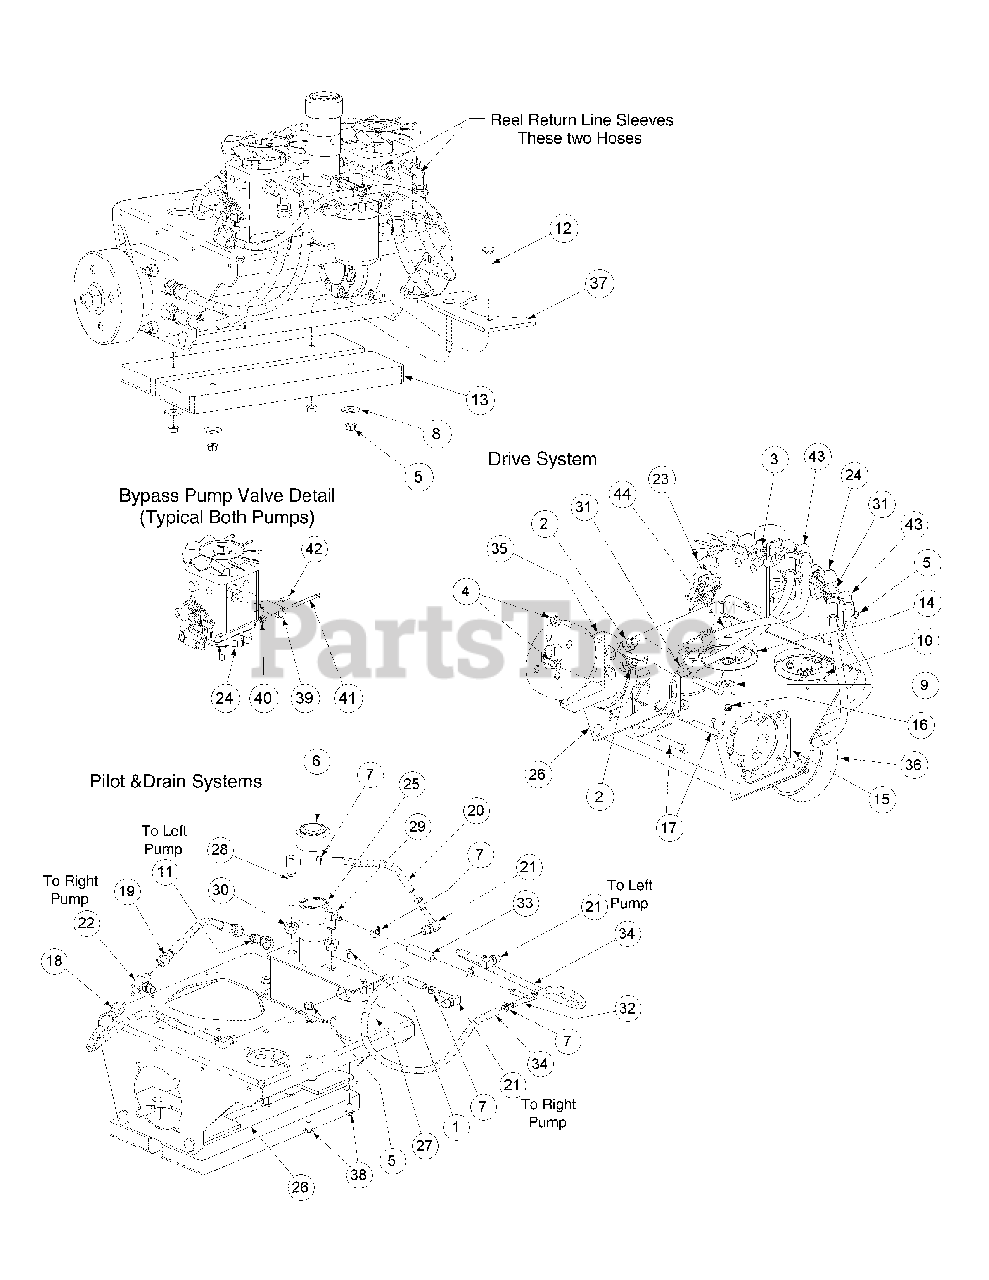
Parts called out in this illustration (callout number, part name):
1	Hex Cap Screw, 1/4-20 x 1/2
2	Fitting 1/2 x 3/4 - O Ring
3	Fitting 1/2 x 3/4 - O Ring to Flare
4	Lock Nut, Nylon Insert, 1/2-13
5	Flange Lock Hex Nut, 3/8-16
6	Cap, Hydro Oil Tank
7	Hose Clamp
8	Flat Washer, .411 x 1.25 x .100
9	Bell Washer, .396 x 1.14 x .095
10	Carriage Screw, 3/8-16 x 1.25
11	Elbow Fitting, 3/8 x 3/8
12	Carriage Bolt, 3/8-16 x 3.5 Lg
14	Hydro Pulley Pump
15	Motor Plate
16	Hex Nut, 3/8-24
17	Socket Head Capscrew, 1/2-13; 2-3/4
18	Hose Assembly Inlet Pump
19	Hose Assembly Inlet Connector
20	Drain Hose, 3/8
21	Fitting, 90 Degree O-Ring
22	Tee Fitting, O-Ring
23	Hydro Pump. RH
24	Hydro Pump, LH
25	Hydro Tank Weldment
26	Engine Mount Weldment
27	Filter Head 1/2
28	Elbow Fitting, Tube Steel
29	Elbow Fitting, w/o Tube Steel
30	Grommet Fitting, .54 ID x .78 OD
31	Pressure Hose Assembly
32	Tee Fitting
33	Hose, 3/8
34	Hose, 3/8
35	Hyd. Motor, White Right Hand
36	Hyd. Motor, White Left Hand
37	Deck Plate
38	Carriage Bolt, 3/8-16 x 0.75
39	Bypass Pump Adaptor Assembly
40	LockNut, 1/4-20, Nylon Insert
41	Socket Head Capscrew, 1/4-20 x 2-1/2
42	Roll Pin, .25 x .875
43	Pressure Hose Assembly, Short
44	Key, 3/16 x 7/8
45	Reel Return Line Sleeve, 1.25
